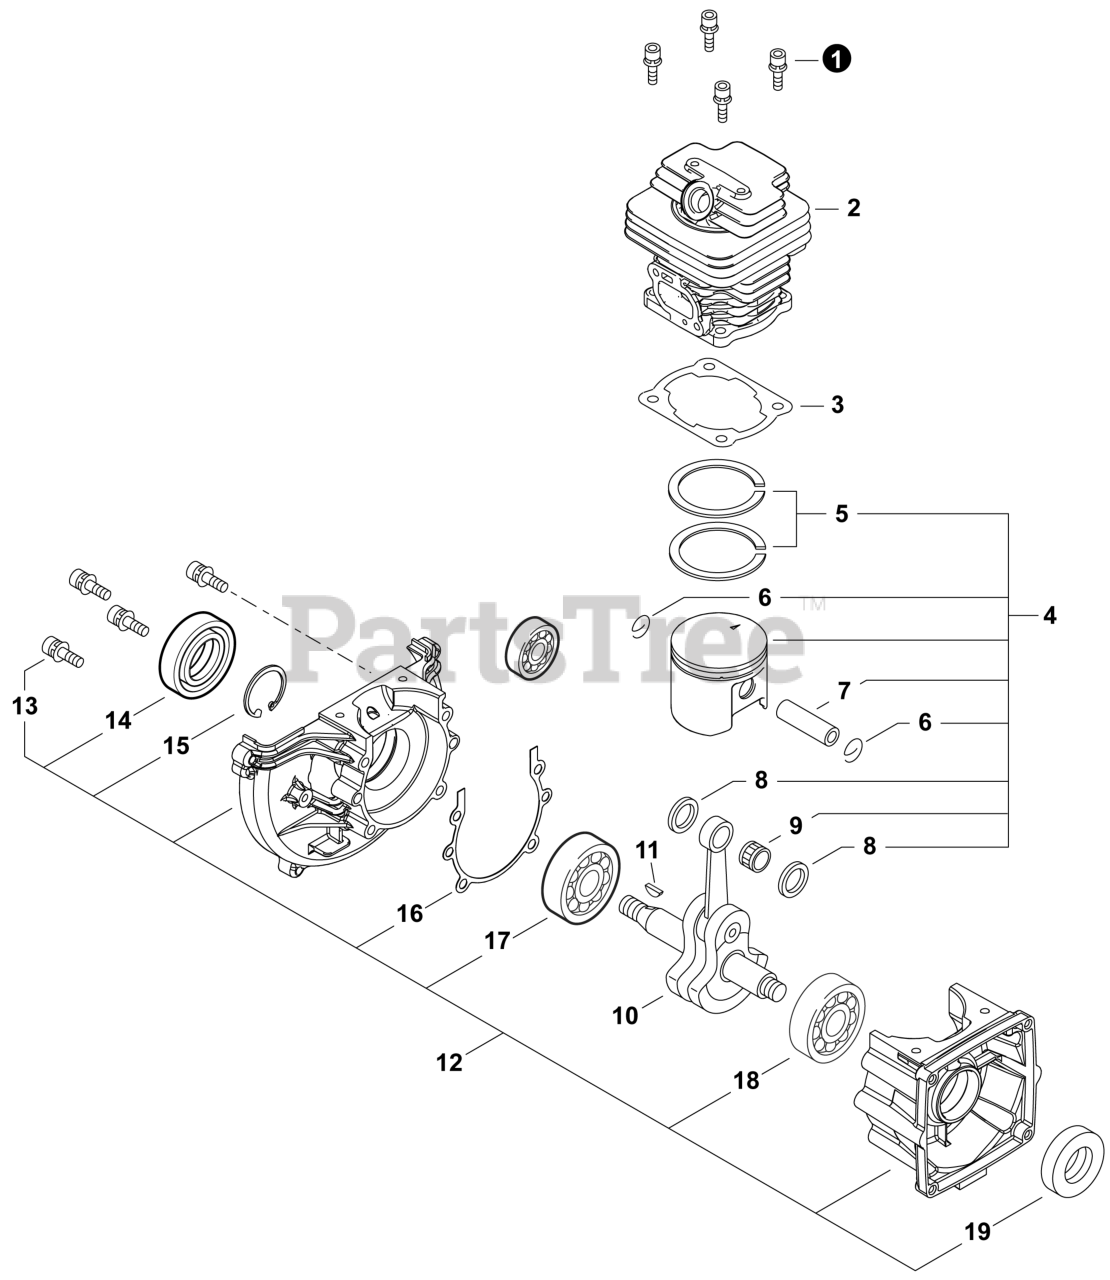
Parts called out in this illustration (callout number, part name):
1	BOLT 5x20
2	CYLINDER
3	GASKET, CYLINDER
4	PISTON KIT
5	RING, PISTON
6	RING, SNAP 10
7	PIN, PISTON
8	WASHER, THRUST 10
9	BEARING, NEEDLE 10
10	CRANKSHAFT ASSY
11	KEY, WOODRUFF
12	CRANKCASE SET
13	BOLT 5x30
14	SEAL, OIL 15
15	RING, SNAP 35
16	GASKET, CRANKCASE
17	BEARING, BALL
18	BEARING, BALL 6201
19	SEAL, OIL 12
